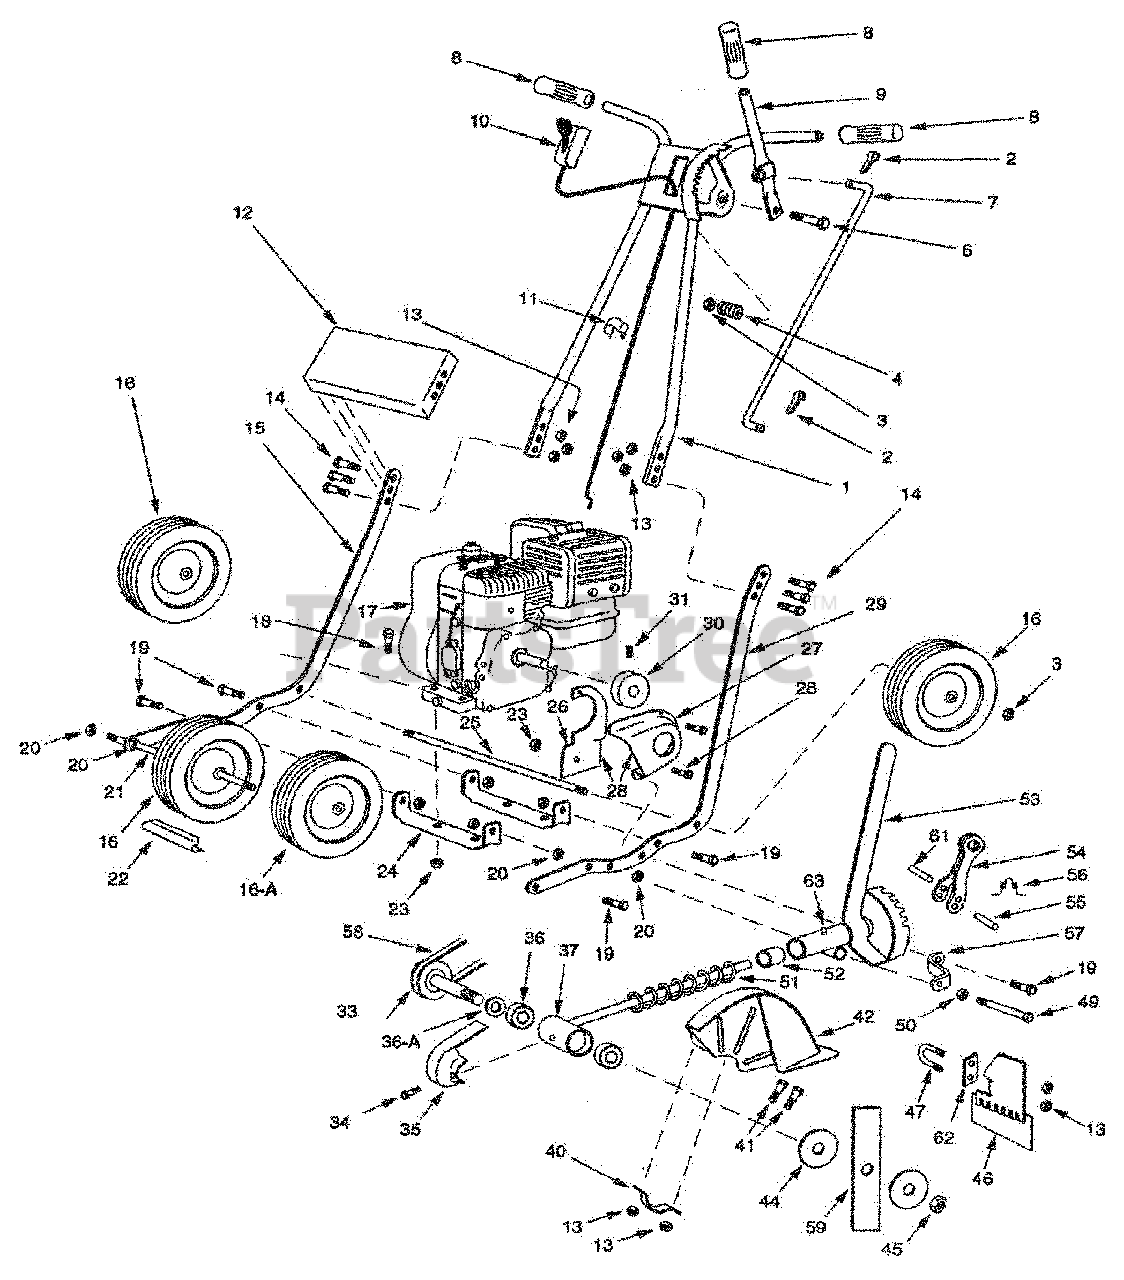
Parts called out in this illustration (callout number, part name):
2	Pin, Cotter 1/8 x 3/4 (2 Req.)
3	Nut Lock Hex 7/16" - 14 (4 Req.)
6	Bolt, Hex 7/16 - 14 x 2
7	Rod, Clutch & Depth
8	Grip (3 Req.)
9	Lever, Clutch & Depth
10	Throttle Control (3 HP Ball Brg) (40-3/4)
11	Clip, Throttle Cable
12	Cross Brace for Handle
13	Nut 1/4-28 Hex (10 Req.)
14	Bolt 1/4-28 x 7/8 hex (6 Req.)
15	Frame, Right Hand 8"
16	Hub Cap for 7" & 8" Rear Wheels
16A	8" Front Wheel Complete w/Bearing & Wide Tire
17	Engine
18	Bolt 5/16-24 x 1-1/2 (4 Req.)
19	Bolt 5/16-24 x 7/8 Hex (5 Req.)
20	Nut 7/16-14 Hex (3 Req.)
21	8" Front Axle
22	8" Front Wheel Spacer (2-13/16" Use With 7075-7 Wheels)
23	Nut 5/16-24 Hex (9 Req.)
24	8" Fram Crossmember
25	8" Rear Axle (13-5/8") (Use with 7058 wheels)
26	Bracket, Engine Pulley Guard
27	Guard, Engine Pulley
28	Engine Pulley Guard & Bracket Complete
28	Screw #10 x x1/2 Sheet Metal (4 Req.)
29	8" Fram, Left Hand
30	Engine Pulley
31	Set Screw 5/16-24x5/16
33	Cutterhead Pulley & Shaft Compl.
34	Screw 1/4-20 x 1/2 Hex
35	Cutterhead Pulley Guard
36	Cutterhead Bearing (2 Req.)
36A	Spring Washer (New 01/87)
37	Mandrel, Head
40	Clamp, Blade Guard
41	Bolt 1/4-28 x 1-1/2 Hex (2 Req.)
42	Blade Guard Main
44	Washer, Friction (2 Req.)
45	Nut 1/2-20
46	Deflector, Debris Sweep
49	Pivot Bolt
50	Flat Washer 7/16
51	Spring, Head Recoil
53	Body, Cutterhead
54	Lever, Angle Shifting
55	Pin 5/16 x 2
57	Brace Cutterhead
58	Drive Belt (4L-300)
59	Cutting Blade
62	U-Clamp Spacer
63	Grease Fitting
